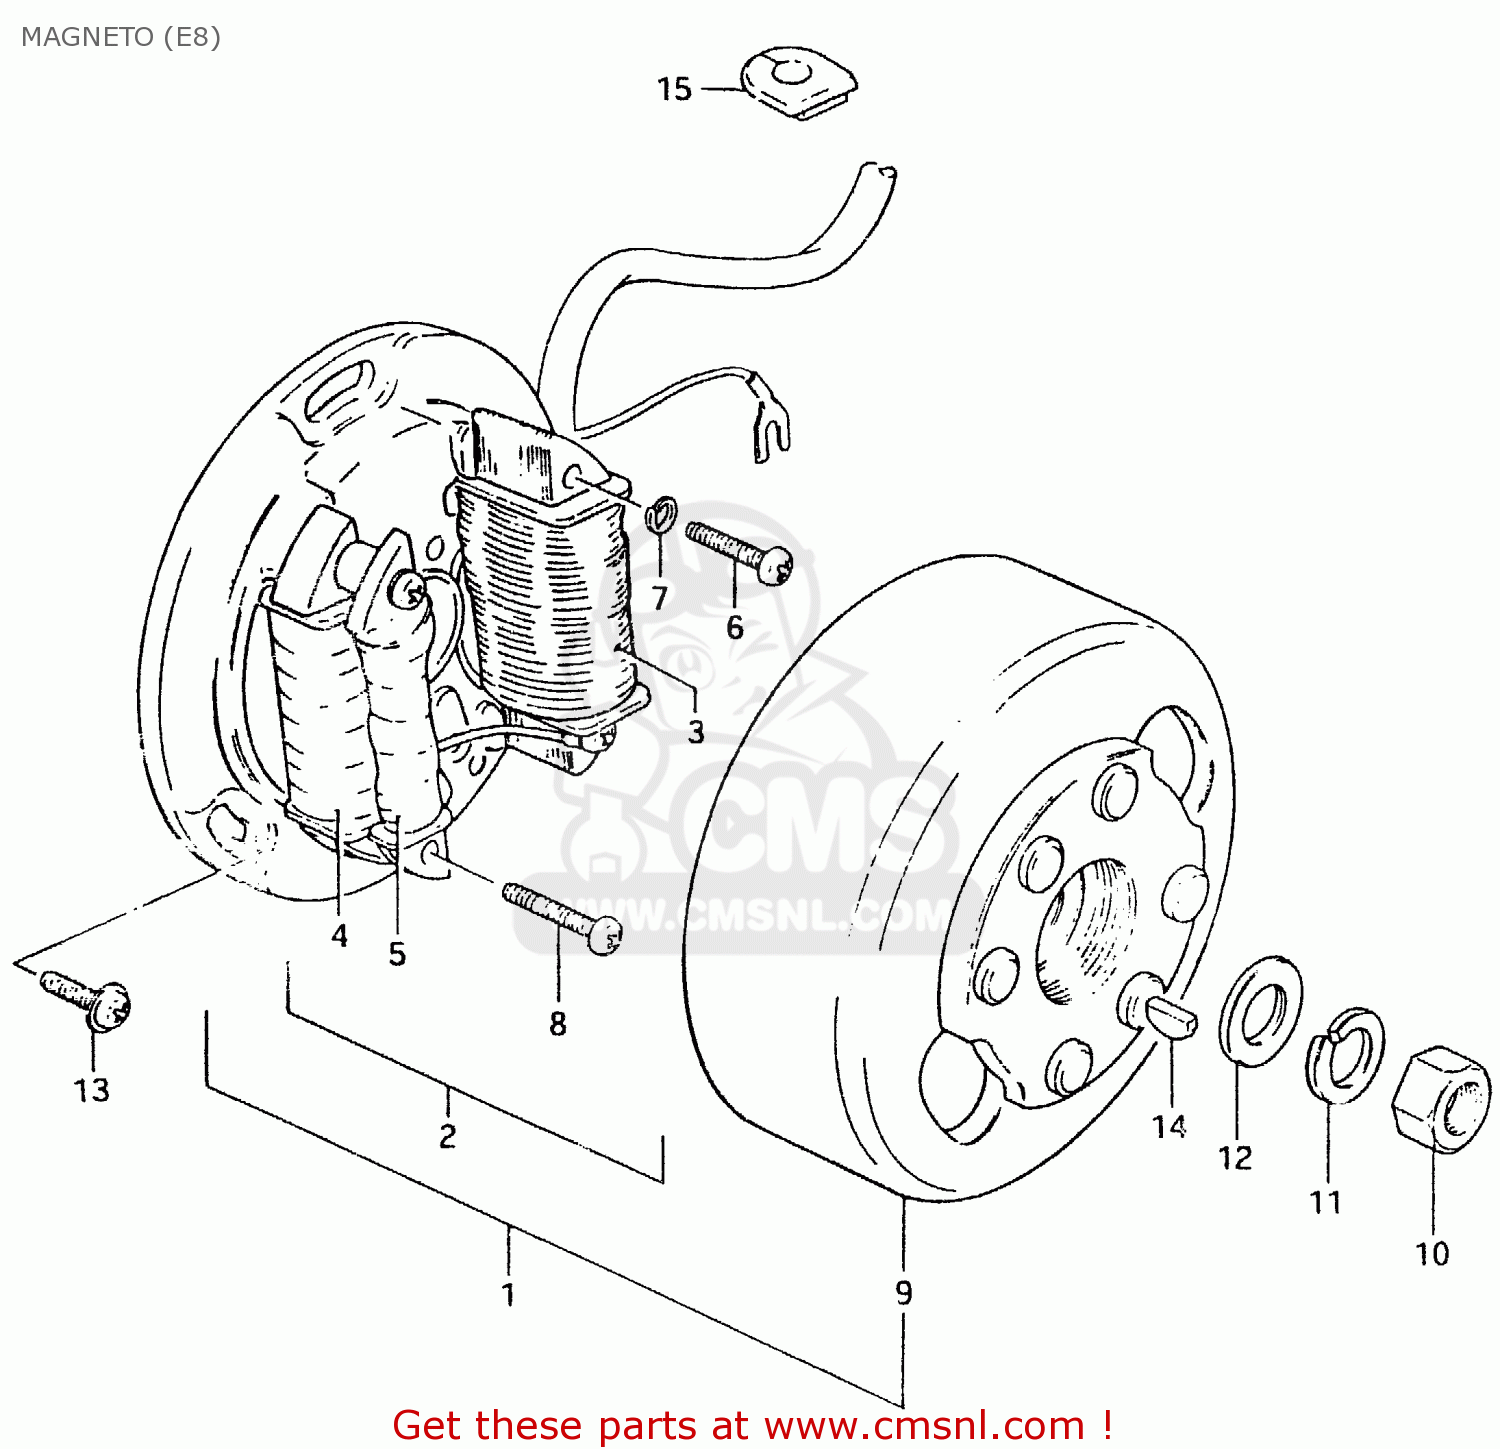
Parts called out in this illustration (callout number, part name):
1	MAGNETO ASSY
2	STATOR ASSY
3	COIL,LIGHTING
4	COIL,PRIMARY
5	COIL,PULSER
6	SCREW 4X25
7	LOCK WASHER
8	SCREW
9	ROTOR
10	NUT (10MM)
11	LOCK WASHER
12	WASHER
13	SCREW(5X14)
14	KEY
15	GROMMET
